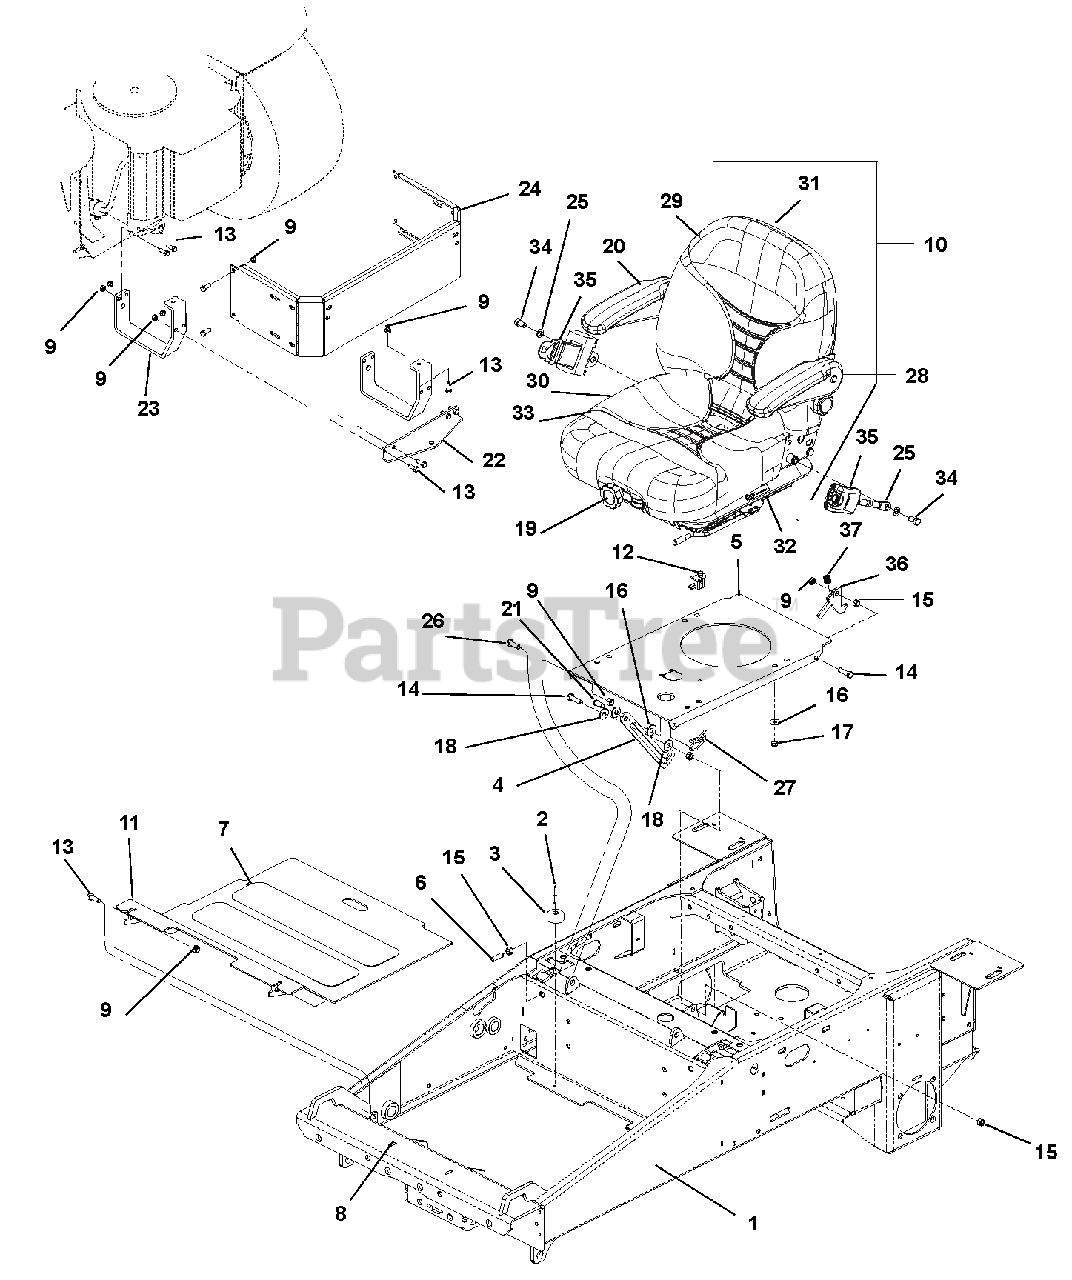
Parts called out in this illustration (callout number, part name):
1	FRAME WITH DECALS ACM
1	ASSY, FRAME WIH DECALS PROZOOM
2	RIVET, 3/16 X .500 POP ST
3	BUMPER, RUBBER .625 X 1.50 DIA
4	BAR, SEAT LOCK
5	PLATE, SEAT
6	SET SCREW, 3/8-16X1.25 SK CUP
7	TAPE, NON-SLIP - 4.00 X 18.00
8	TAPE, NON-SLIP - 2.50 X 21.50
9	NUT-LK-FLG .375-16 PL
10	SEAT-SUSP-LT GRY-SEAT BLT BUSH
11	WLDT, FOOT PLATE
12	SWITCH- SNAP MTG N.O.
13	@BLT-HEX .38-16X1.00 GR5 YWZC
14	@BLT-HEX .38-16X1.25 GR5 YWZC
15	@NUT-HEX .38-16 YWZC
16	@WSHR-FL-STL.38X.875X.083 YWZC
17	NUT-CROWN .312-18 YWZC
18	@WSHR-FL-STL.438X1.00X.083 YWZ
19	KIT-SEAT KNOB
20	KIT-RH ARMREST ASSEMBLY REPLAC
21	PIN-CLEV .38X.75 YWZC
22	PLATE, HITCH
23	ARM, HITCH SUPPORT
24	PLATE, REAR BUMPER
24	PLATE, GRAVELY BUMPER
25	@WSHR-LK .44X.109 REG YWZC
26	BLT-SHLDR .5X1.06X.38-16 SLD 5
27	RING, RUE .375 X .054 X 1.254
28	KIT-LH ARMREST ASSEMBLY REPLAC
29	KIT-BACK CUSHION-LIGHT GRAY
30	KIT-SEAT CUSHION-LIGHT GRAY
31	KIT-SEAT BACK PANEL
32	KIT-SEAT SLIDE
33	KIT-SPRING AND SADDLE
34	@BLT-HEX .44-20X.75 GR5 YWZC
35	ASSY, SEAT BELT
36	LATCH, SEAT
37	SPRING, COM .600X.056X.875 Y
